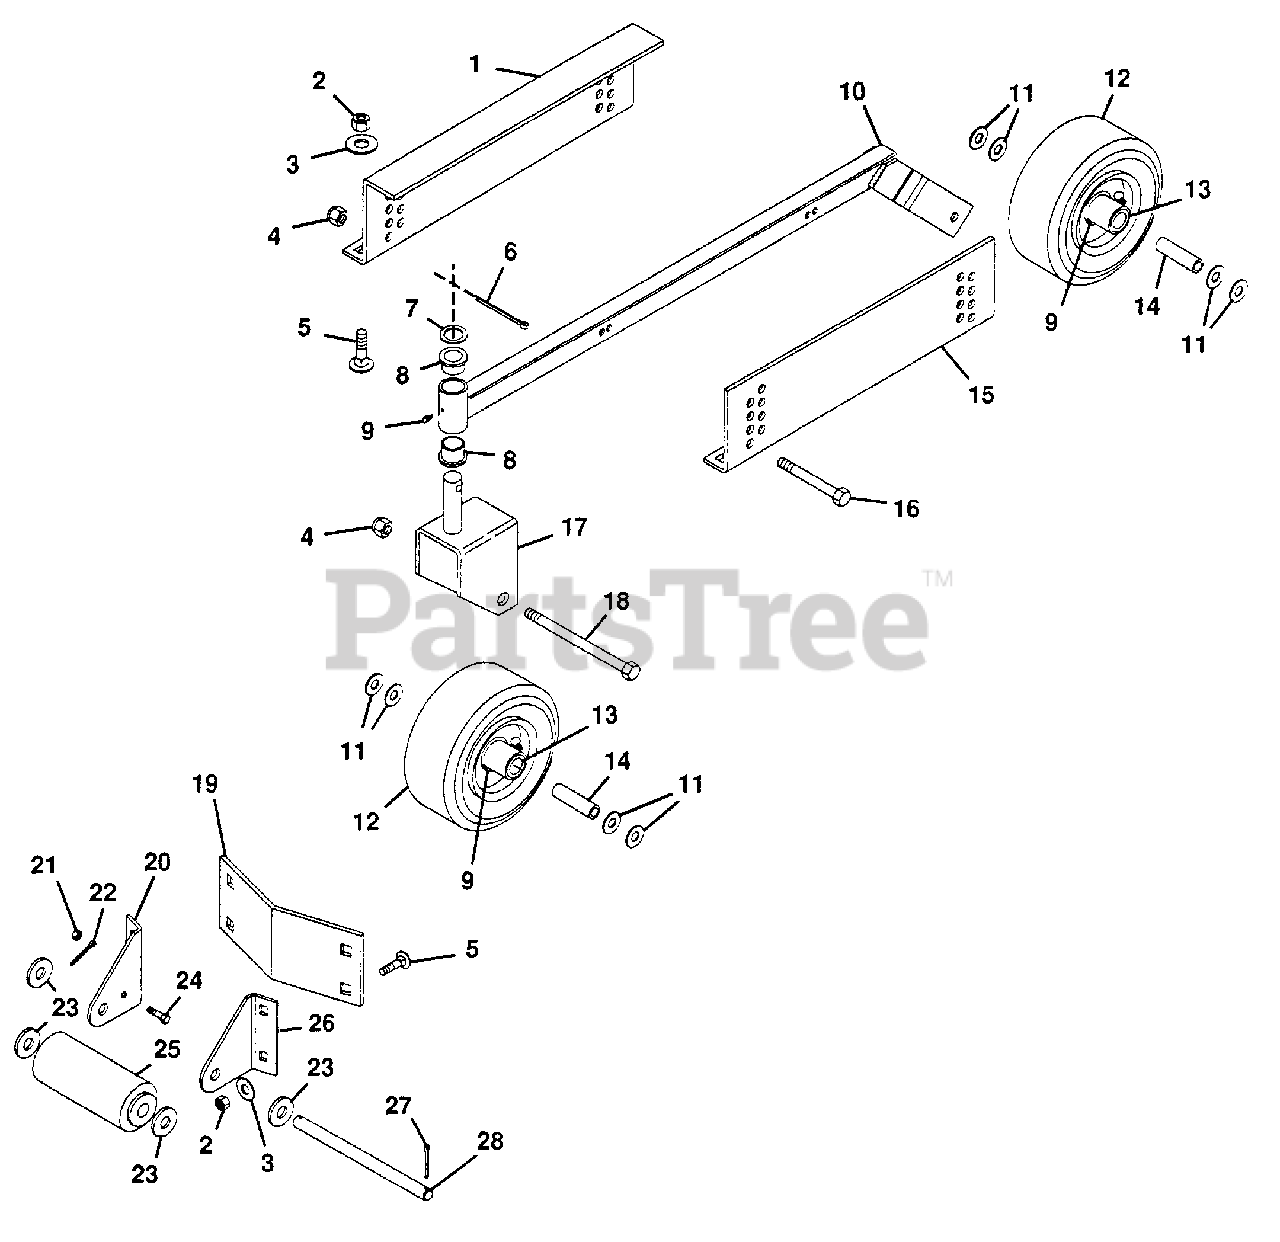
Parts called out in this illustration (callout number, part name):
1	Hanger, Inner
2	Nut, Lock 3/8-16
3	Washer, Flat .406x.812x.065
4	Nut, Lock 1/2-13
5	Bolt, 3/8-16x1.00 Rd Hd Sq Nk
6	Pin, Cotter .187x1.625
7	Race, Bearing Thrust
8	Bush., Flg. 1.03x1.75x.75 Ny.
9	Fitting, Lube 1/4-28
10	Weldment, Caster Support
11	Washer, Flat .531x1.250x.100
12	Wheel, Gauge
13	Bearing, Gauge Wheel
14	Bush., St. .506x.748x3.34 Stl.
15	Hanger, Outer
16	Bolt, Hex 1/2-13x3.50
17	Weldment, Caster Fork
18	Bolt, Hex 1/2-13x5.50
19	Plate, Deck Reinforcement
20	Bracket, Roller(R.H.)
21	Nut, Lock 1/4-20
22	Pin, Cotter .250x2.00
23	Washer, Flat .656x1.312x.095
24	Bolt, Hex 1/4-20x.75
25	Roller, Gauge
26	Bracket, Roller(L.H.)
27	Pin, Cotter .25x1.00
28	Shaft, Center Roller
